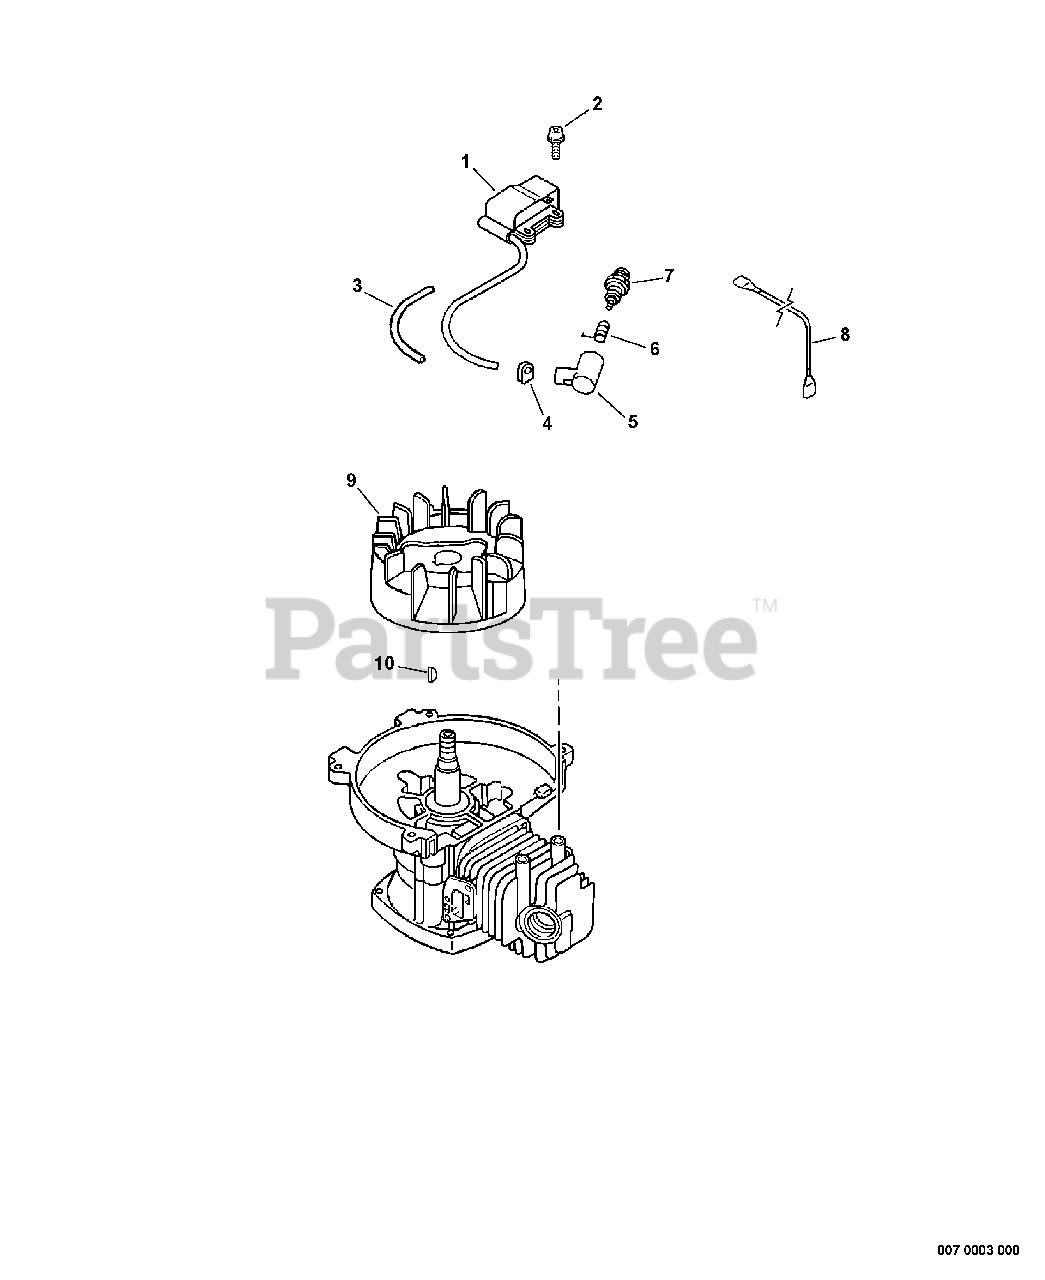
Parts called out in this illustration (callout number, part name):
1	COIL, IGNITION
2	BOLT 4×20
3	TUBE, INSULATOR
5	CAP, SPARK PLUG
6	TERMINAL, SPARK PLUG
7	SPARK PLUG - BPMR7A
8	LEAD - IGNITION
9	FLYWHEEL
